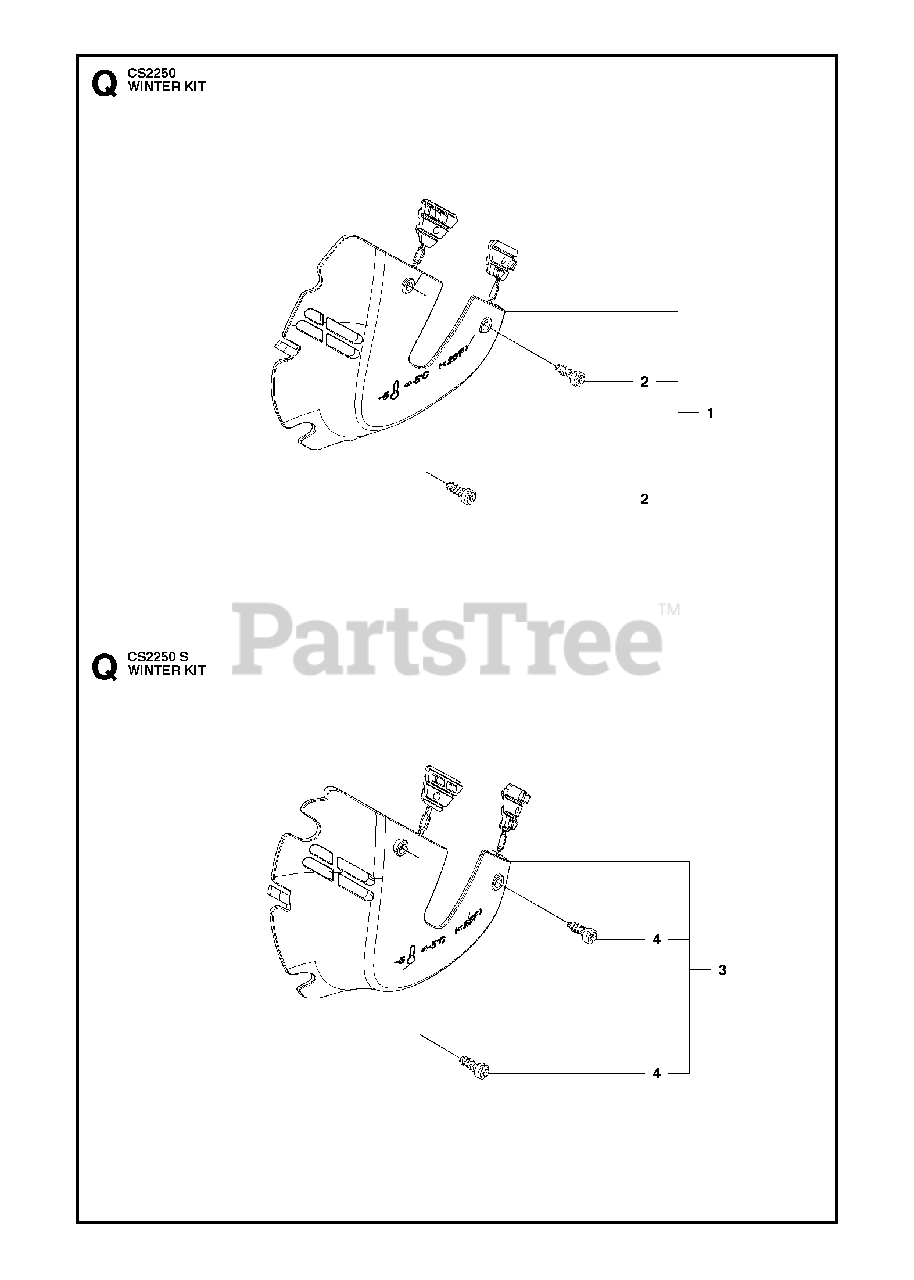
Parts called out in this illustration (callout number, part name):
2	SCREW
3	WINTER KIT
4	SCREW
